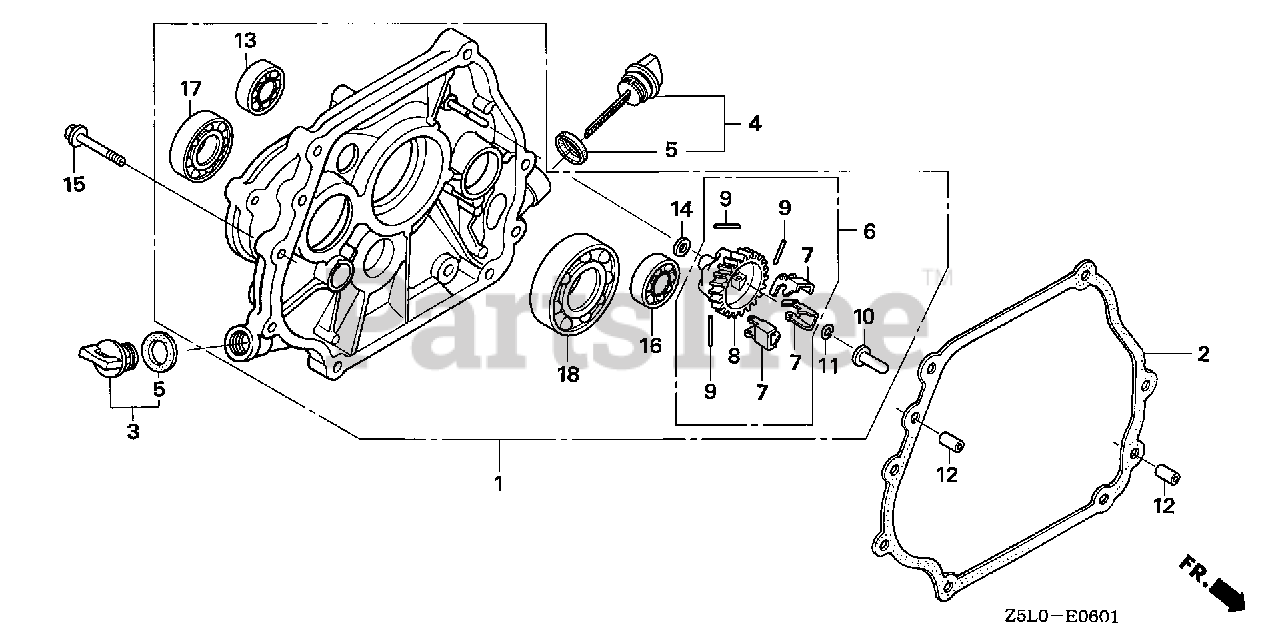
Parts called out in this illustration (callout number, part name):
1	COVER ASSY., CRANKCASE
2	GASKET, CASE COVER
3	CAP ASSY., OIL FILLER
4	CAP ASSY., OIL FILLER
5	GASKET, OIL FILLER CAP
6	GOVERNOR ASSY.
7	WEIGHT, GOVERNOR
8	HOLDER, GOVERNOR WEIGHT
9	PIN, GOVERNOR WEIGHT
10	SLIDER, GOVERNOR
11	CLIP, GOVERNOR HOLDER
12	PIN, DOWEL (8X12)
13	BEARING, RADIAL BALL (6202) (NTN)
14	WASHER, PLAIN (6MM)
15	BOLT, FLANGE (8X40)
16	BEARING, RADIAL BALL (6202)
17	BEARING, RADIAL BALL (6204)
18	BEARING, RADIAL BALL (6207)
